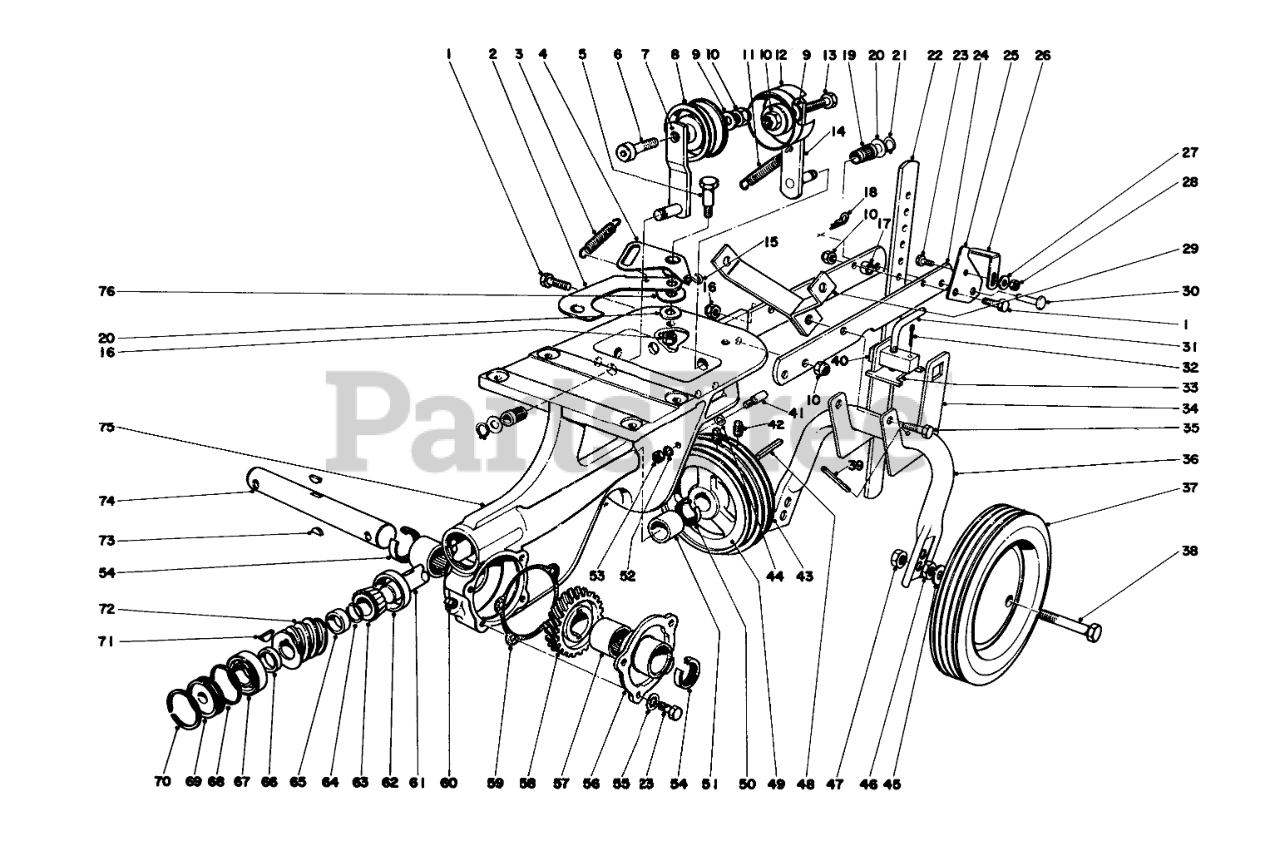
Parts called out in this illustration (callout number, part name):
1	SCREW-HH
2	Rev. Link
3	Spring
4	Bellcrank
5	SCREW-SHOULDER, HH
6	Capscrew
7	IdlerArm
8	PULLEY IDLER
9	WASHER-FLAT
10	NUT-LOCK, CONE
11	Spring
12	IDLER PULLEY
13	SCREW-HH
14	Idler
15	S Hook
16	NUT-LOCK, CONE
17	Spacer
18	PIN-COTTER, HAIR
19	IDLER BRG
20	WASHER-PLAIN
21	RING-RETAINING, EXT
22	DEPTH GAGE
23	SCREW-HH
24	Drawbar
25	Hinge Latch
26	Drag Bar Latch
27	WASHER-FLAT
28	NUT-LOCK, CONE
29	Handle Support
30	TINE PIN
31	Handle Jack
32	PIN-COTTER
33	Jack Plate
34	Axle Saddle
35	SCREW-HH
36	Axle Yoke
37	Wheel
38	Axle
39	PIN-SPRING
40	Jack Nut
41	Belt Guide
42	SCREW-SET, HSH
43	Pulley
44	WASHER-FLAT
45	WASHER-FLAT
46	NUT-JAM
47	1/2-13 CONELOCK NUT
48	KEY-SQUARE
49	Pulley
50	SEAL-OIL
51	BUSHING
52	WASHER-LOCK/EXT
53	NUT-JAM
54	SEAL-OIL
55	Lockwasher
56	Cover
57	Bearing
58	WORM WHEEL
59	GASKET
60	PLUG-PIPE, SQH
61	WORM SHAFT
62	1.750 ROLLER BRG CUP
63	3/4 ROLLER BRG CONE
64	RETAINER RING
65	WORM SHF REAR SPACER
66	SPACER
67	.750 BALL BEARING
68	O-RING
70	INTRNL RETAINING RING
71	KEY-WOODRUFF
72	WORM GEAR
73	KEY-WOODRUFF
74	WORM WHEEL SHAFT
75	Chassis
76	WASHER-FLAT
